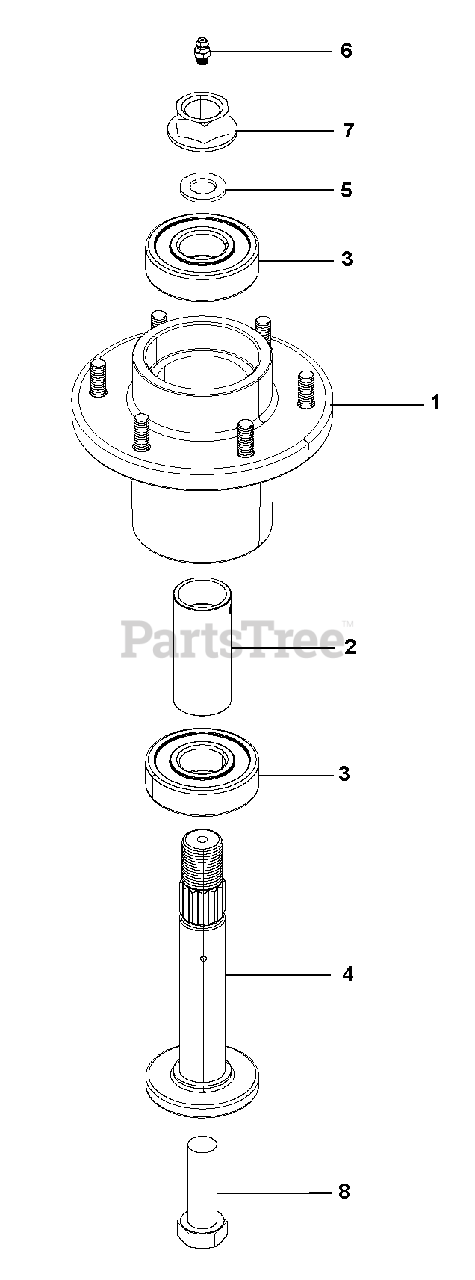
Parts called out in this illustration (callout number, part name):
1	Casting, Spindle w/Studs
2	Spacer, 1.250 x 1.000 x 2.780
3	Bearing, 6305LLC
4	Shaft, Spindle .75-16
5	Washer, .75 x 1.3125 x .120
6	Fitting, .25-28 STRGT Grease Zerk
7	Locknut, .75-16 Crown
8	Bolt, .625-11 x 2.00 Hex 8
